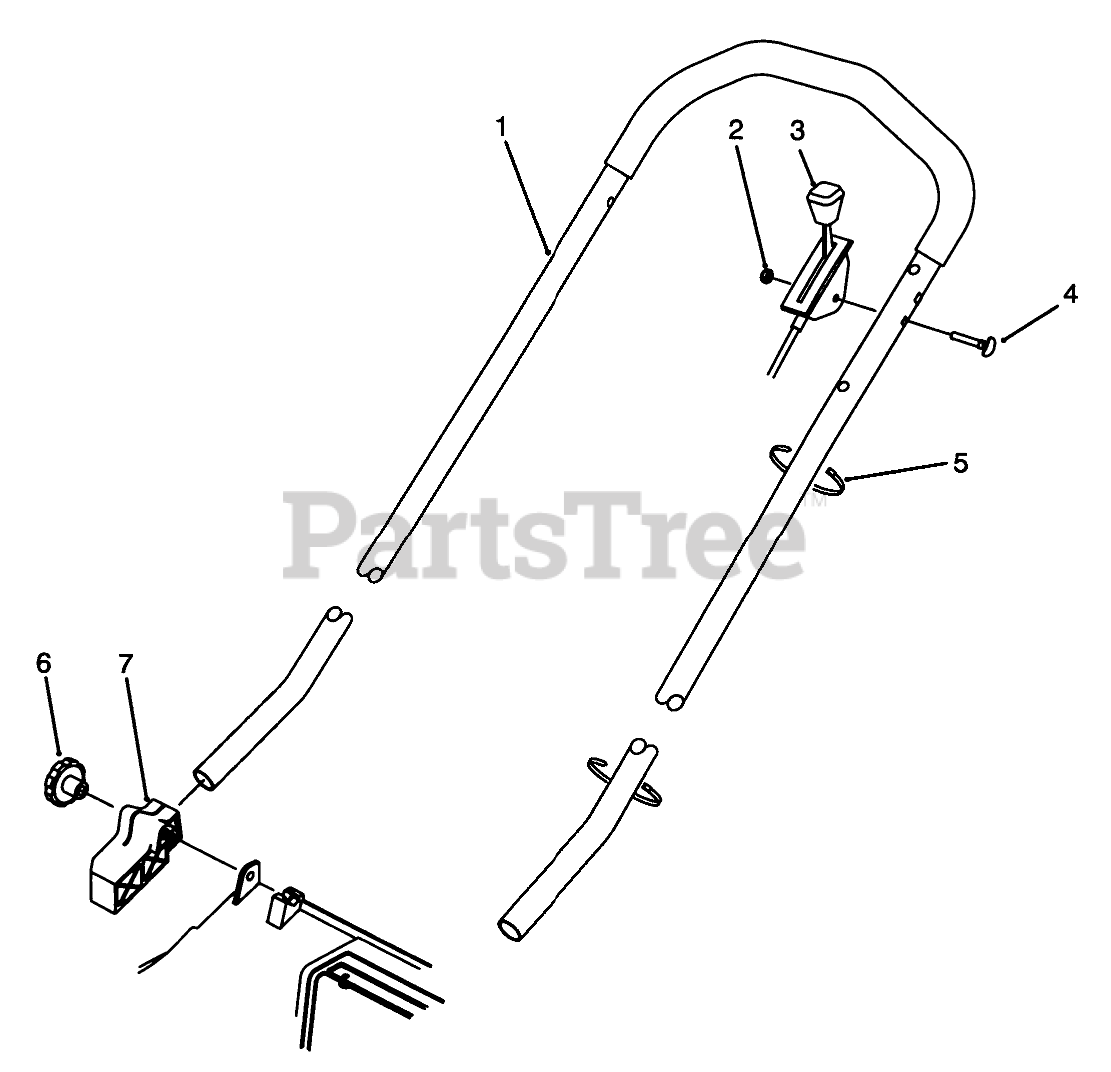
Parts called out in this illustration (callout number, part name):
1	HANDLE (DIPPED)
2	NUT-LOCK, NI
3	THROTTLE CONTROL
4	SCREW-HANDLE
5	TIE-CABLE
7	MOUNT-HANDLE, RH
